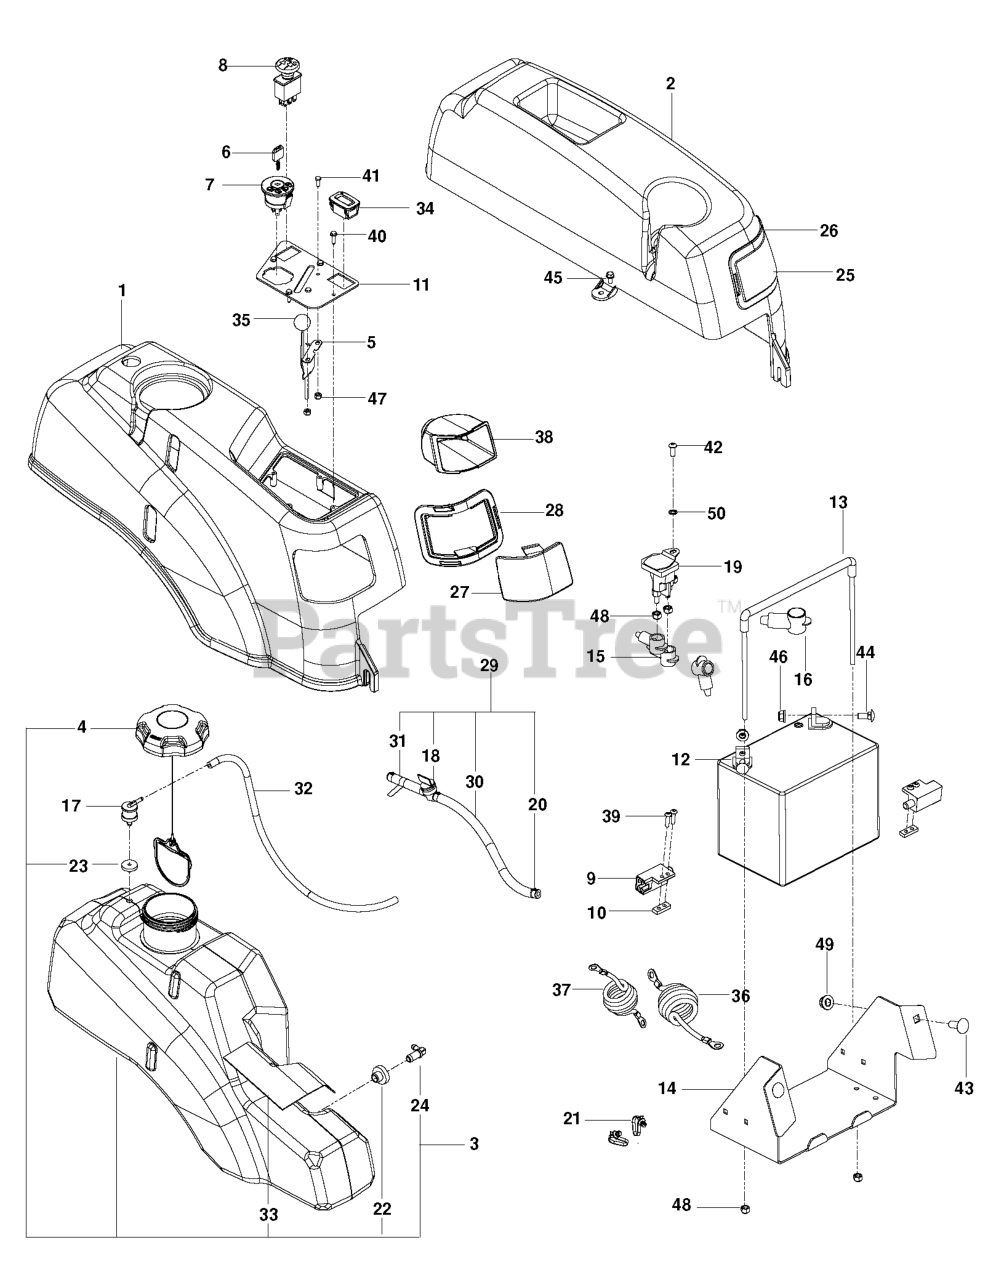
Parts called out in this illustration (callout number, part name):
1	FENDER RT, GRAY
2	FENDER, LT
3	TANK.FUEL.ASSEMBLY.LARGE
4	CAP, FUEL
5	CABLE.THROTTLE.37"
6	KEY MLD GEN DELTA
7	RP IGNITION SWITCH
8	RP SWITCH.PTO.8.TERMINAL.RED
9	SWITCH INTERLOCKT
10	PLATE NUT ZTR
11	PLATE.CONTROL.R/START.RZ.X431
12	BATTERY, 12 V 330 AMP
13	BATTERY TIE DOWN ASSEMBLY
14	BOX, BATTERY, BLACK
15	TERMINAL COVER
17	VALVE.FUEL.CHECK
18	FUEL VALVE
19	SOLENOID.W/BRASS.PLUNGER
20	HOSE CLAMP
21	TIE WRAP, 8-3/8", W/CLIP
22	RUBBER GROMMET
23	GROMMET, CHECK VALVE
24	STEM, FUEL TANK
25	LEFT HEADLIGHT LENS
26	LEFT HEADLIGHT RIM GREY
27	RT HEADLIGHT LENS
28	RT HEADLIGHT RIM GREY
29	FUEL LINE ASSY
30	GAS LINE 10"
31	FUEL LINE 3"
32	HOSE, FUEL, 3/16" X 17-1/4"
33	SHIELD, HEAT
34	RP.GUAGE.SRVCMNDR.HRMTR.
35	KNOB.ROUND.BALL.BLACK
36	CABLE POSITIVE, LONG
37	BATTERY CABLE, NEGATIVE
38	REFLECTOR, LEFT HEAD LIGHT
39	SCR #10-24 X .75 SKT HD BLK
40	SCR #10-12X3/4 HEX WAS HD ZD
41	HCS #10-24 X 1/2
42	SCR 1/4-20 X 5/8 BTN SKT HD ZD
43	BOLT D
44	RP BOLT 5/16-18 X3/4 ZN/YEL GR
45	SCREW
46	NUT 3/8-16 HEX FLG NYLOC ZD
47	NUT 10-24 NYLOC
48	LOCKNUT.NYLOC.1/4-20
49	5/16-18 NYLOC FLANGE NUT
50	WASHER 1/4 INT TOOTH
